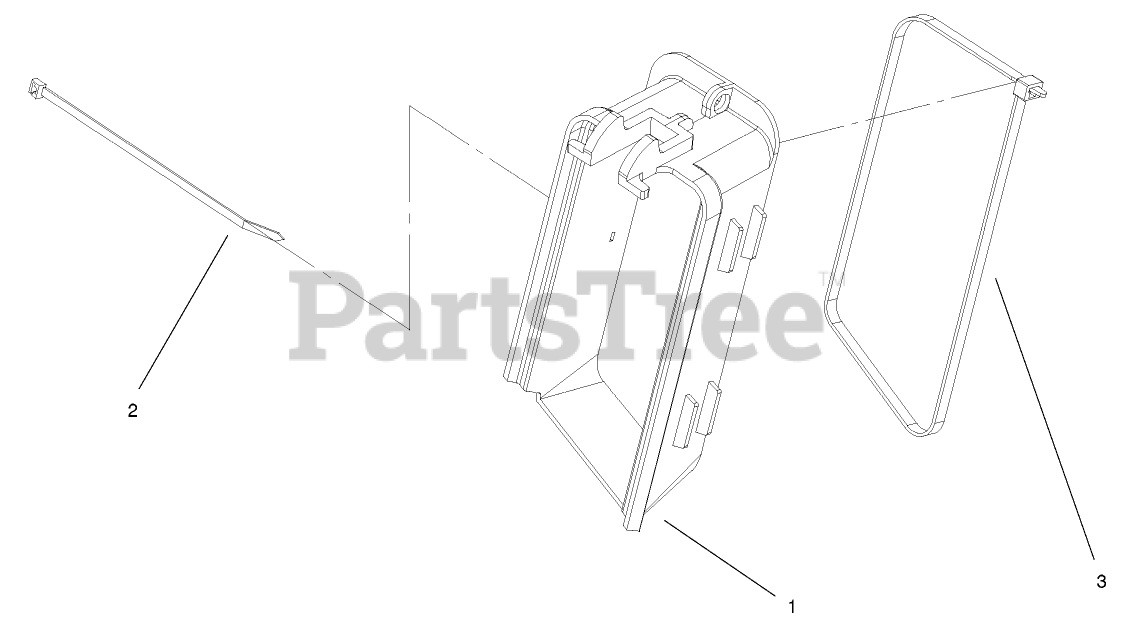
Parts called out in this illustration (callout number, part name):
1	Chute-Bag,Inlet
2	TIE-CABLE
3	STRAP-TIE
